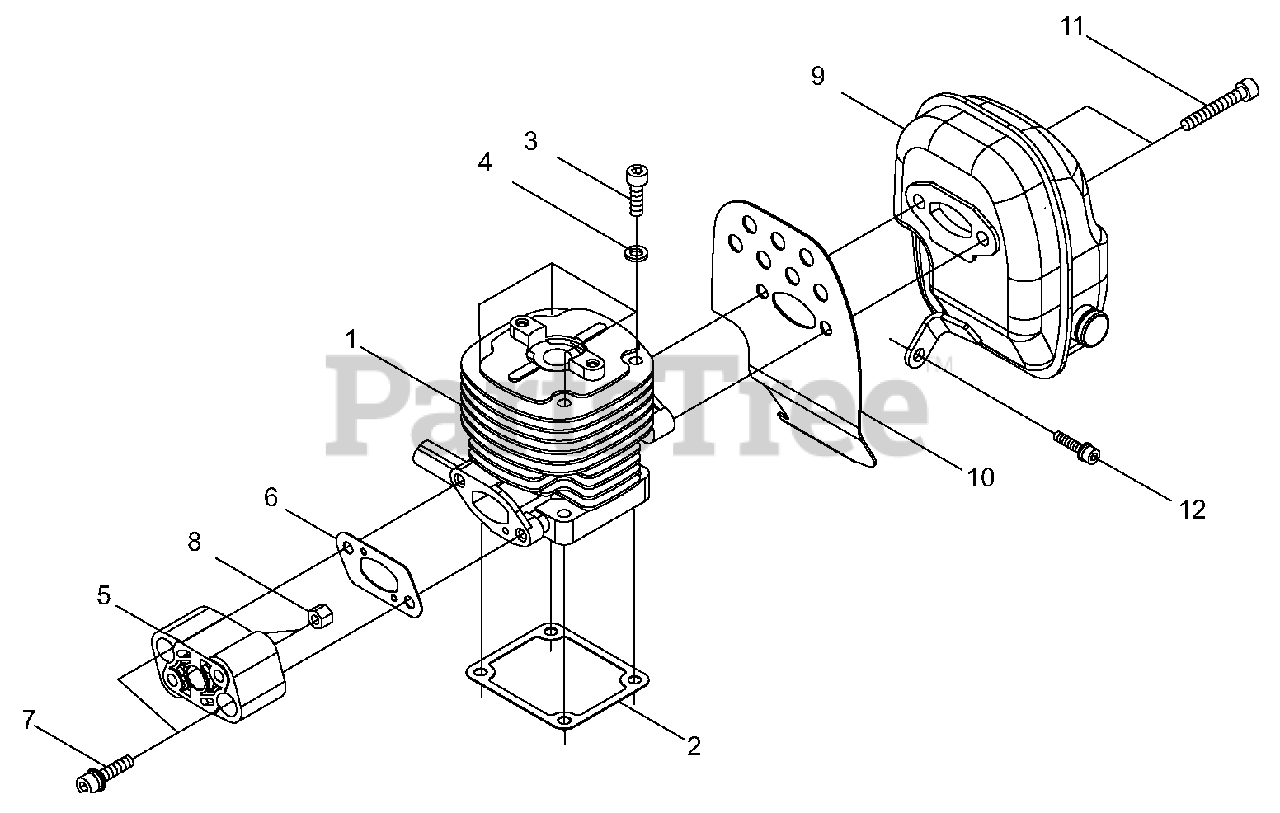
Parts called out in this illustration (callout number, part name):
1	CYLINDER
2	GASKET, CYLINDER
3	SCREW - 5X25
4	LOCKWASHER - 5
5	INSULATOR, INTAKE
6	GASKET, INTAKE
7	SCREW - 5X25
8	NUT - 5X6.3
9	MUFFLER
10	SHIELD, EXHAUST
11	SCREW - 6X25
12	SCREW - 5X12
